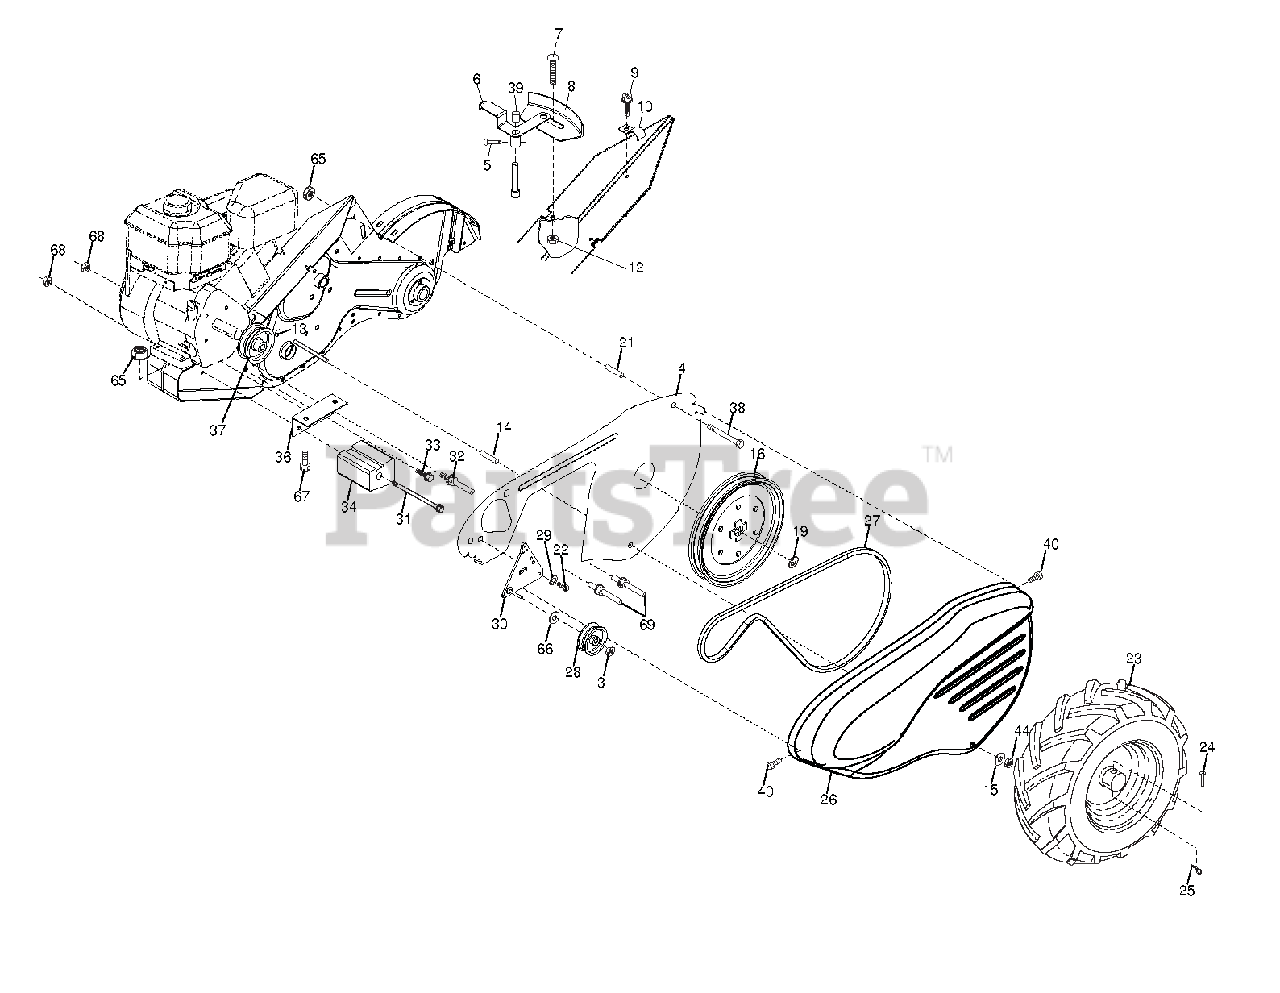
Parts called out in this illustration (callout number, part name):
3	Nut, Hex 3/8-16
4	SHIELD, INNER BELT GUARD
5	Pin, Shift Lever
6	Lever, Shift
7	Bolt 1/4-20 unc x 1/2 Gr. 5
8	Plate, Shift Indicator
9	Screw, Tap Hex Head
10	Clip, Cable
12	Nut, Keps Hex 1/4-20 unc
13	Screw Set 5/16-18 x 3/8 Patch
14	Spacer, Split .327 x .42 x 2.0
15	Washer 11/32 x 11/16 x 16 Ga.
16	Sheave, Transmission
19	Ring, Retainer
21	Spacer, Split .327 x .42 x 1.2
22	Bolt, Hex Head 5/16-24 unf x 1
24	Rivet, Drilled
25	Retainer Spring
26	Guard, Belt
27	Belt, V
28	Pulley, Idler
29	Ring, Klip
30	Bracket, Idler
31	Bolt, Hex 5/16-16 x 12
32	Shaft, Idler Arm
33	Bolt, Hex 3/8-16 x 1
34	Counterweight, LH
36	Bracket, Reinforcement, LH
37	Sheave, Engine
38	Bolt, Fin Hex 5/16-18 x 2-3/4
39	Cap, Plunger
40	Screw Hex Wsh Hd #8-18 x 1/2
44	Locknut, Washer Insert 5/16-18
65	Nut, Hex, Flangelock
66	Washer 13/32 x 13/16 x 12 Ga.
67	Bolt, Hex Head, Gr. 25/16-18 x
68	Nut Keps Hex 3/8-16 unc
69	KEEPER BELT ENGINE
